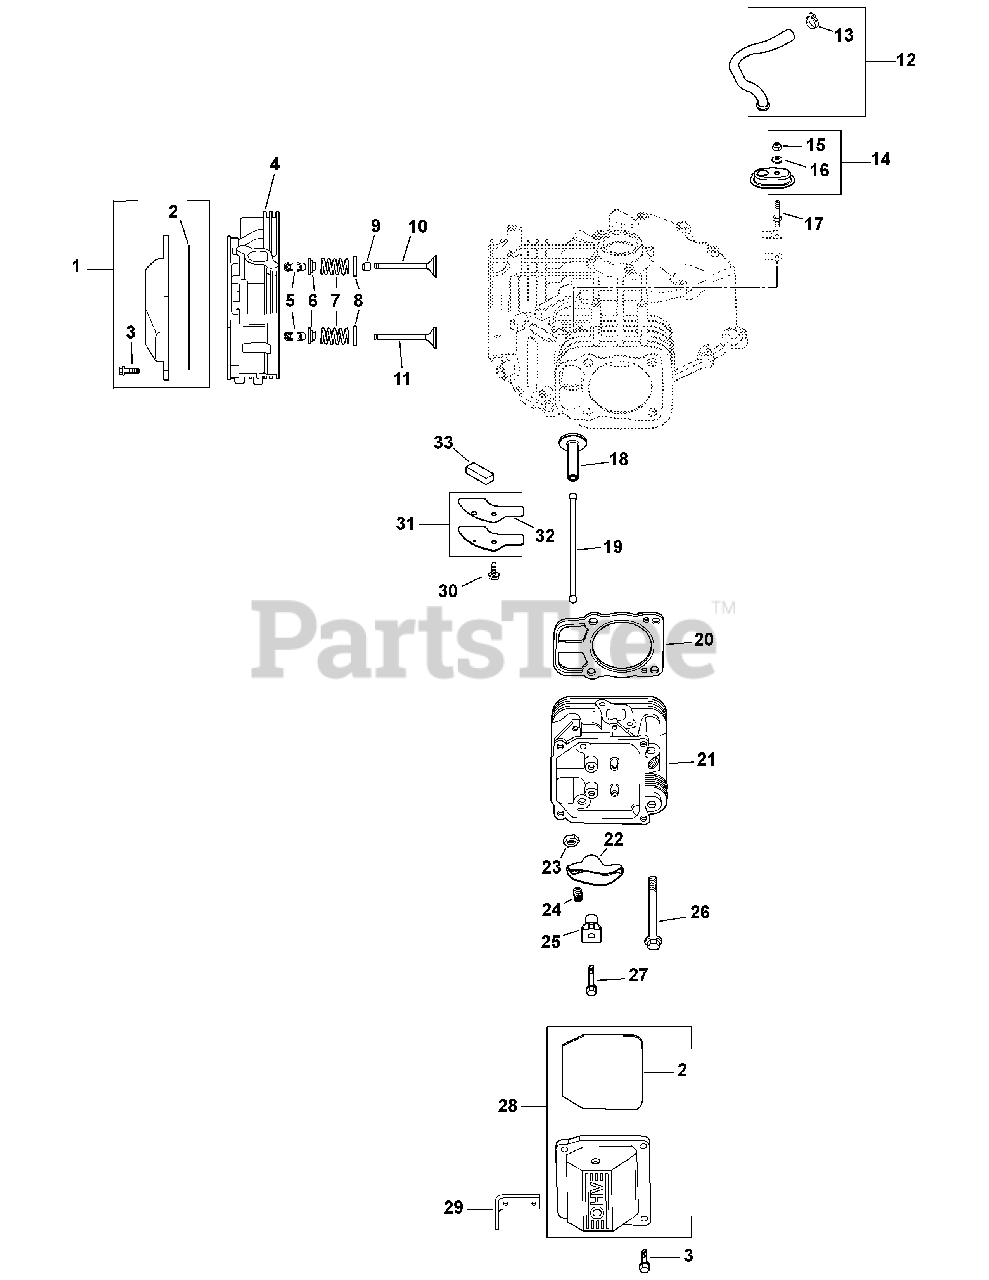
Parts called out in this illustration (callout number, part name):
1	Kit, Rocker Cover
2	O-Ring, Valve Cover
3	Screw, Flnge M6 x 1.0 x 30
4	Kit, #1 Cylinder Head
5	Kit, Retainer
6	Cap, Valve Spring
7	Spring, Valve
8	Retainer, Spring
9	Seal, Valve Stem
10	Valve, Intake (Std.)
11	Valve, Exhaust (Std.)
12	Kit, Breather Hose, (Incl. 1pc Ref. 13)
13	Clamp, Hose
14	Kit, Breather Housing (Incl. 15,16)
15	Nut, Lock, M5 x 0.8
16	Washer, Sealing
17	Stud, Breather Cover
18	Kit, Tappet
20	Kit, Cylinder Head Gasket
21	Kit, #2 Cylindre Head
22	Arm, Rocker
23	Nut, M10 x 0.75
25	Pivot, Rocker Arm
26	Screw, Flange, M10 x 1.5 x 90
27	Screw, Flange, M6 x 1.0 x 45
28	Kit, Breather Valve Cover (Incl. 1pc Ref.2)
29	Strap, Lifting
30	Screw, Flnge Thrd. Frmng M6 x 1.0 x 16
31	Kit, Breather Cover (Incl. Ref. 32)
32	Gasket, Breather Cover
33	Filter, Breather
